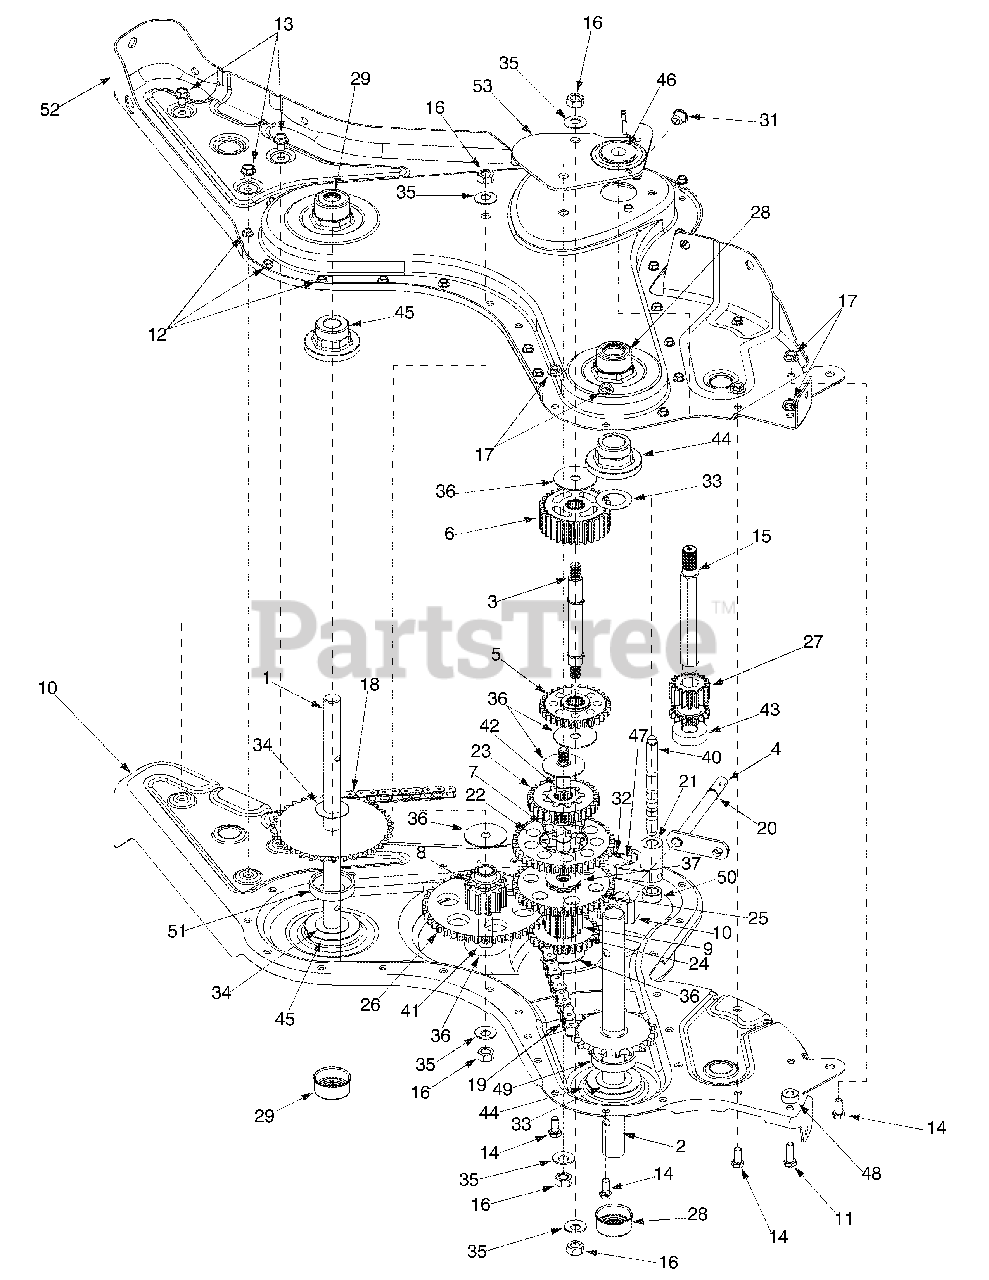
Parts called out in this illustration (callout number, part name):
1	Wheel Shaft Ass’y 33T
2	Tine Shaft Ass’y: 18T
3	Jack Shaft Ass’y
4	Input Shaft Ass’y
5	Rev. Idler Gear Ass’y: 30T
6	Tine Idler Gear Ass’y: 30T
7	Tine Input Sprocket Ass’y: 9T
8	Wheel Input Sprocket Ass’y: 10T
9	Gear Ass’y: 11T
11	Hex Bolt 5/16-18 x 1" Lg.
12	Hex S-Tap Scr. 1/4- 20 x.5"
13	Hex S-Tap Scr. 5/16-18 x.625"
14	Hex Bolt 5/16-18 x.75"
15	Input Shaft
16	Hex Nut 7/16-20
17	Flange Nut 5/16-18
18	#420 Chain 1/2 Pitch x 50 Links
19	#50 Chain 5/8 Pitch x 54 Links
20	Snap Ring
21	Shifting Fork
22	Spur Gear 44T
23	Spur Gear 30T
24	Spur Gear 30T
25	Spur Gear 44T
26	Spur Gear 44T
27	Spur Gear 16T
28	Seal 1.0 Shaft
29	Seal.75 Shaft
31	Taper Cap Ring
32	Compression Spring.50" Leg.
33	Thrust Wash. 1.03" ID X.1.62"
34	Fl-Wash.76" ID x 1.5" OD
35	Bell-Wash .45" ID x 1.0"
36	Thrust Wash. .445 x 1.92
37	Fl-Wash. .635" ID x 1.59
40	Detent Shaft 1/2" Dia.
41	Jack Shaft .625 x 2.385
42	Jack Shaft .625 x 5.0
43	Ball Bearing
44	Flange Bearing 1.0 x 2.5 x 1.38
45	Flange Bearing .75 x 2.5 x 1.38
46	Ball Bearing . 6692 x 5745 x .466
47	Detent Ball .250
48	Spacer .315
49	Spacer 1.0 I.D x 2.0 OD x .440
50	Spacer .505 ID x .88 OD x .440
51	Spacer .75 x 2.0 x .50
53	Gear Positioner Bracket
